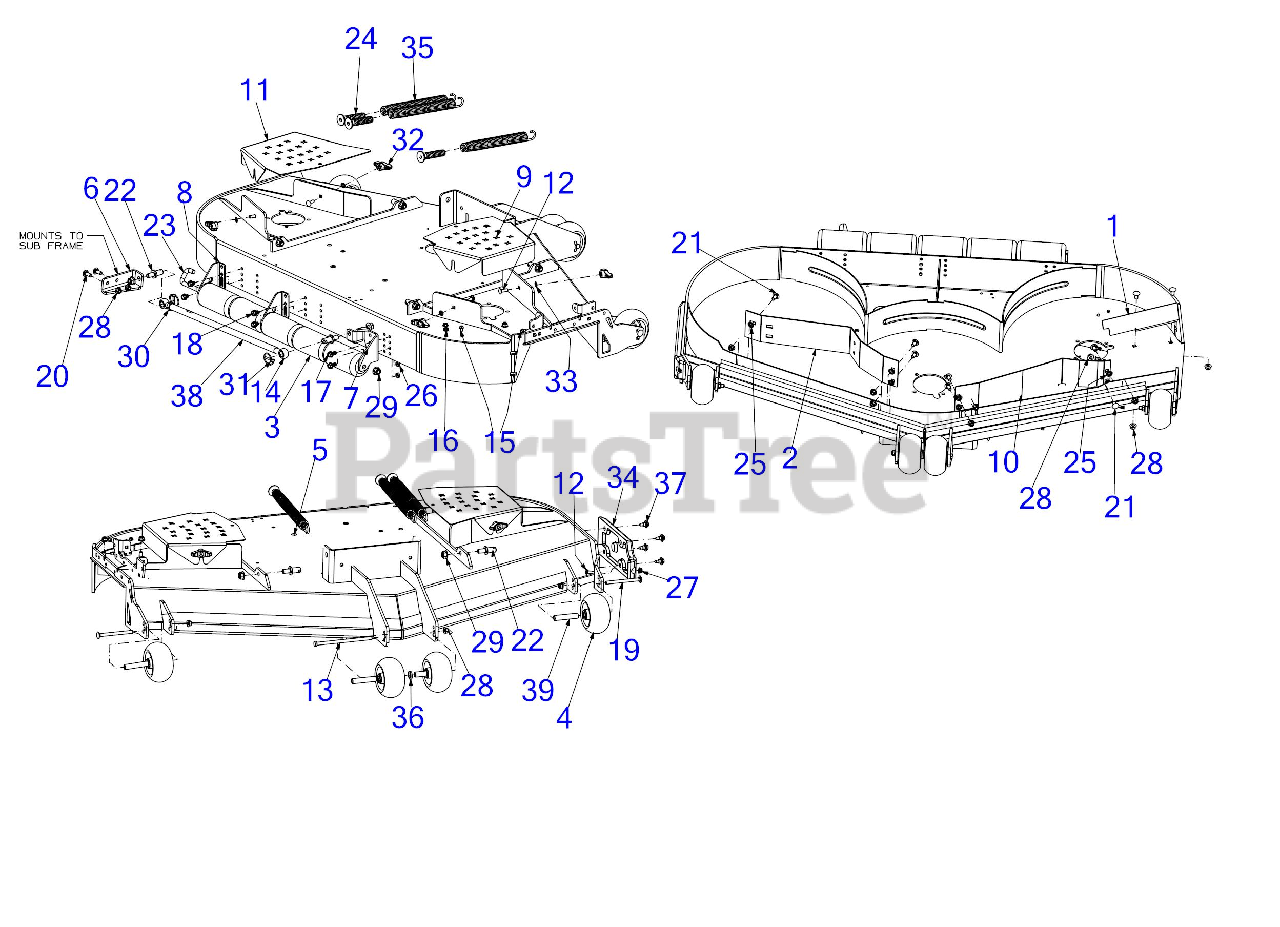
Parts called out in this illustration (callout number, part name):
3	ROLLER ASSEMBLY
4	WHEEL ASSEMBLY 5"
12	CARRIAGE BOLT 5/16-18 x 1.00
13	SCREW 3/8-16 x 7.25 GR5
14	BOLT 5/8-16 x 2.63
15	SCREW 1/4-20 X.500
16	SCREW 5/16-18 x .500
17	SCREW 3/8-16 x 3/4
18	SCREW 3/8-16 x .500
19	CARRIAGE BOLT 3/8-16 x 4.25 GR5
20	CARRIAGE BOLT 3/8-16 x 1.00 GR5
21	CARRIAGE BOLT 3/8-16 x .75
23	REAR ROLLER PIN
24	SPRING INSERT SCREW
26	JAM LOCK NUT
27	FLANGE LOCK NUT 5/16-18
30	HEX NUT
32	WING KNOB 5/16-18
34	DECK SKID PLATE (LH)
35	EXTENTION SPRING 1.20 x 11.35
36	FLAT WASHER .632X1.00X.16
37	SHOULDER SCREW .43X.29X5/16-18 TT
39	WHEEL SPACER .38ID x 3.04LG
